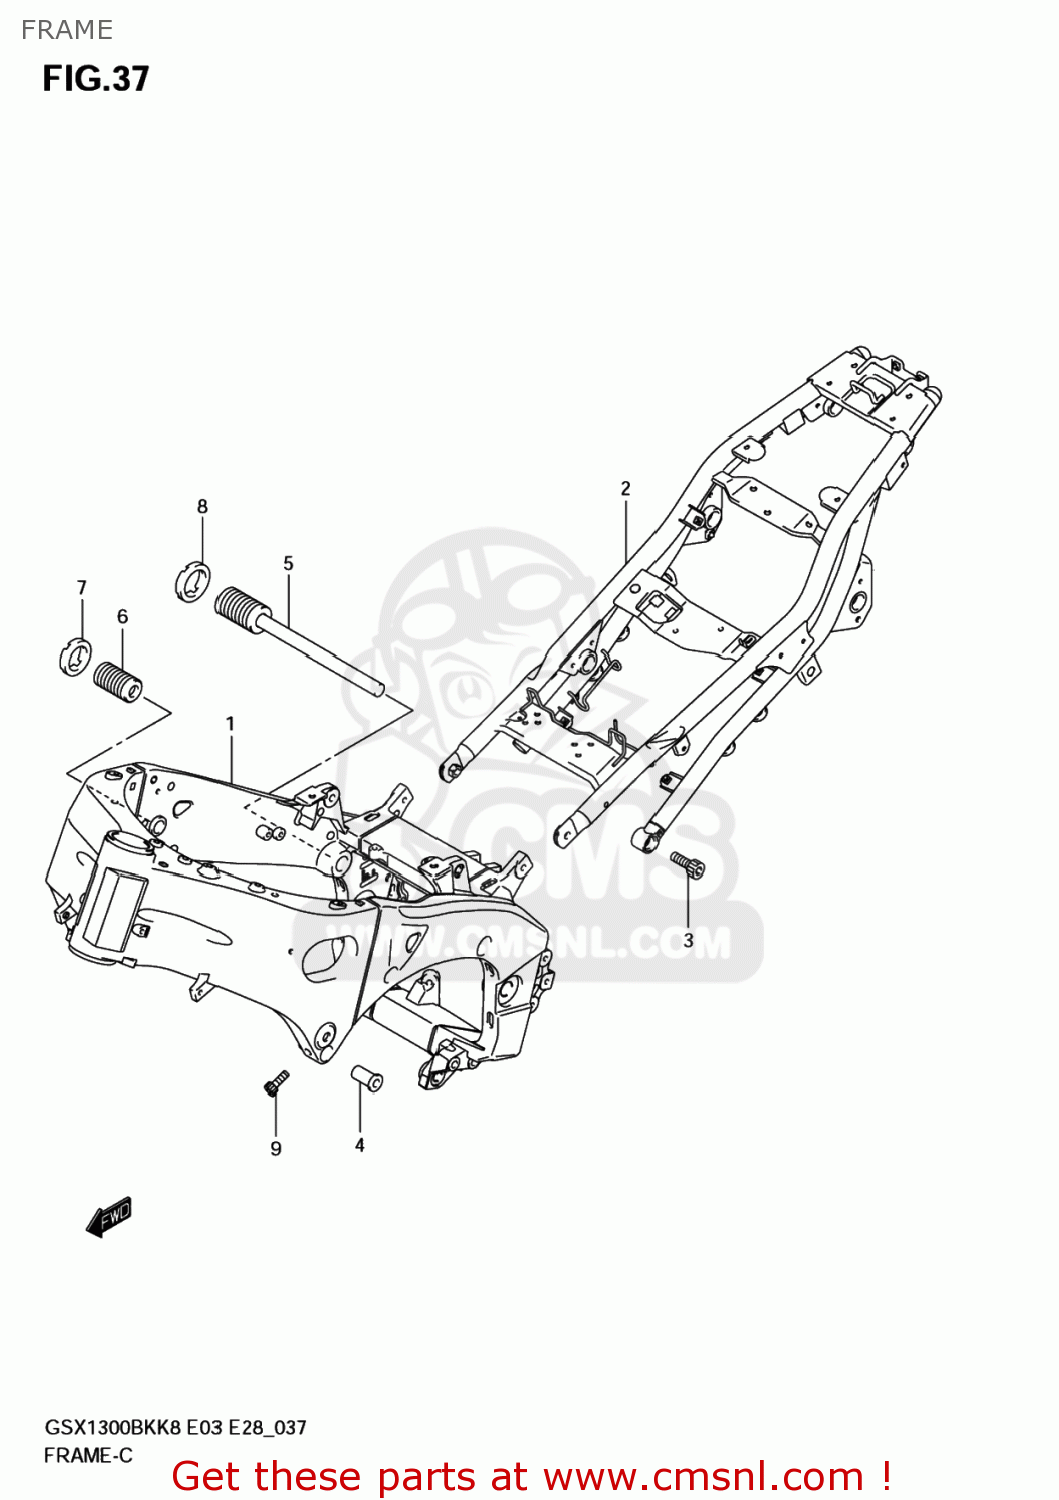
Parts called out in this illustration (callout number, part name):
1	FRAME
2	RAIL,SEAT
3	BOLT(10X35)
4	SPACER,ENGINE MTG
5	BOLT,CRANK CASE ADJUST
6	BOLT,CRANK CAS
7	NUT,ADJUST BOLT
8	NUT,CRANKCASE ADJUST
9	BOLT(8X30)
